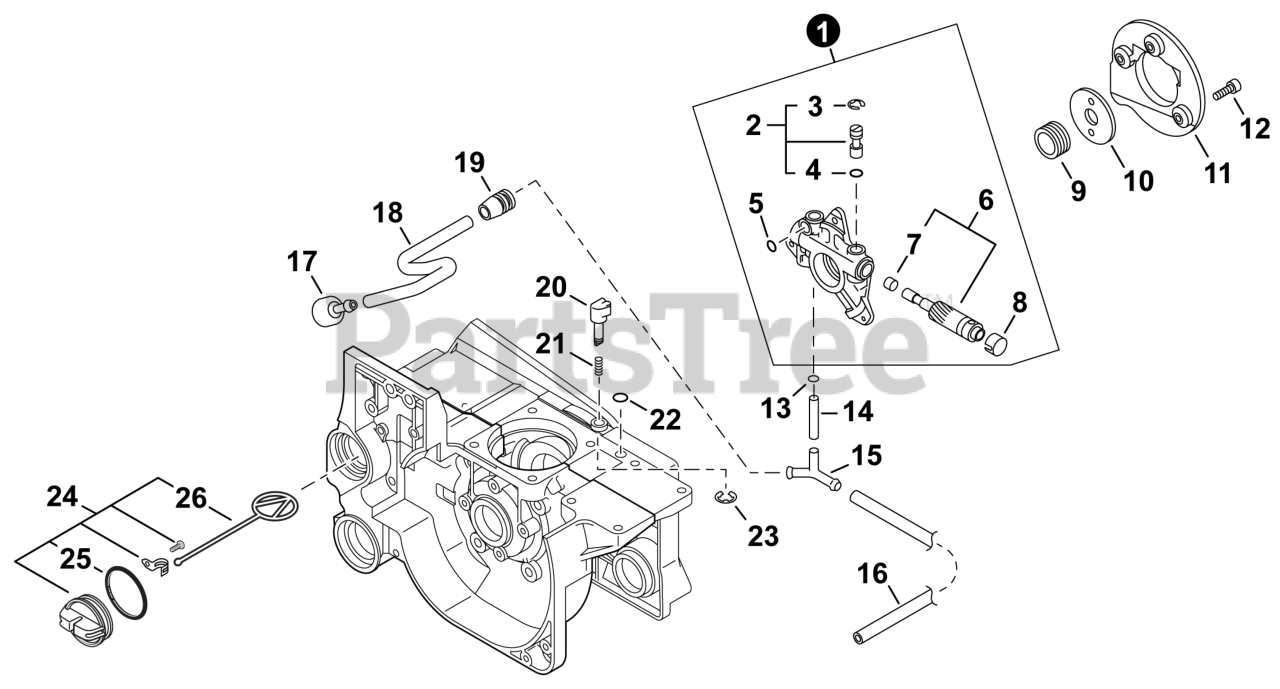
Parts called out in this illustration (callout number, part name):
1	AUTO-OILER ASSY
2	PIN ASSY, CONTROL
5	O-RING 3
6	PLUNGER KIT
8	CAP, PLUNGER
9	GEAR, WORM
11	COVER, OIL PUMP - ORANGE
12	BOLT 4×14
13	CLIP Ø6.5 MM
14	PIPE, OIL 3×6×20
15	CONNECTOR, PIPE
16	PIPE, FUEL 3×6×210 BLACK
17	FILTER, OIL
18	PIPE, OIL
20	ADJUSTER, AUTO-OILER - ORANGE
22	O-RING 3
23	E-RING 3
24	CAP ASSY, OIL
26	FUEL CAP CONNECTOR (L=60MM)
